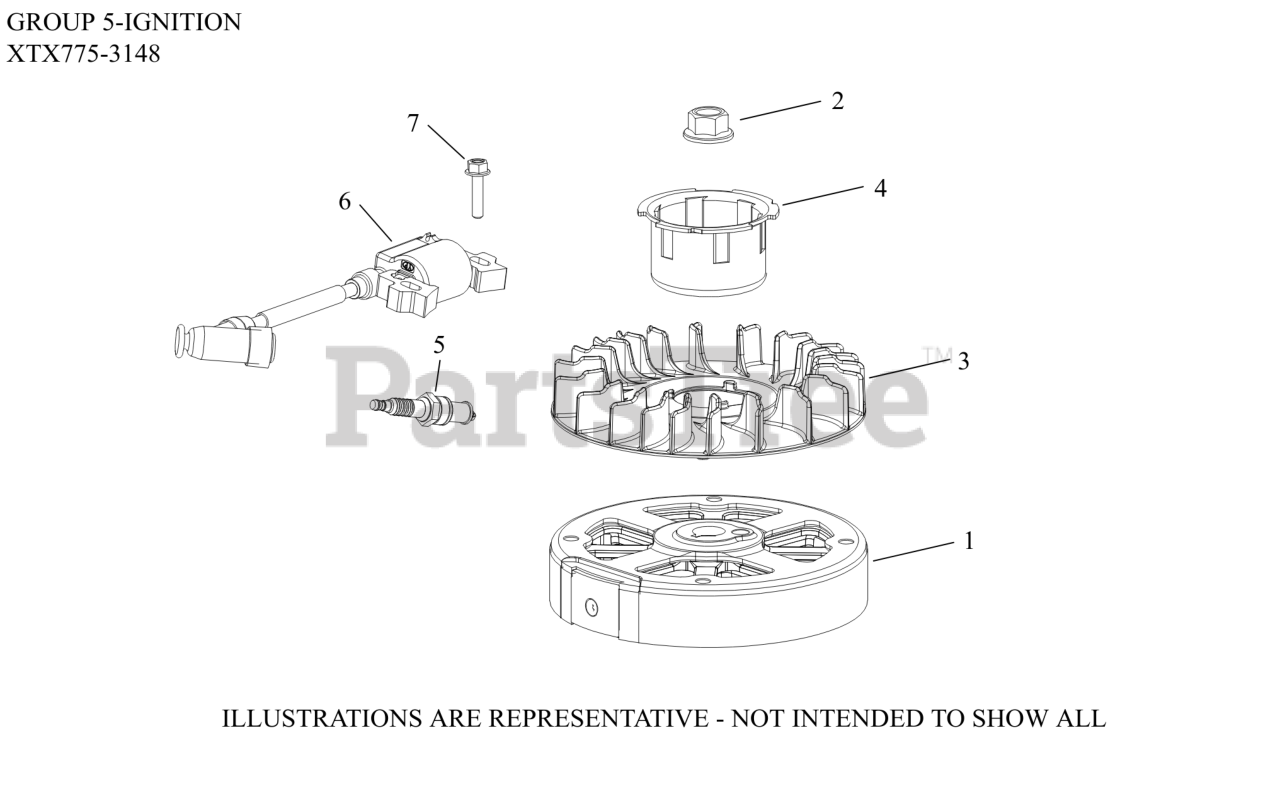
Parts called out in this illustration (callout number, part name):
1	FLYWHEEL (CAST IRON)
2	NUT, FLYWHEEL (W/SERRATIONS)
3	FAN, FLYWHEEL
4	CUP, DRIVE - (#1410905S)
5	PLUG SPARK 12MM RFI
6	MODULE IGN (#1458416S)
7	SCREW, M6 X 25-(#25086436S)
